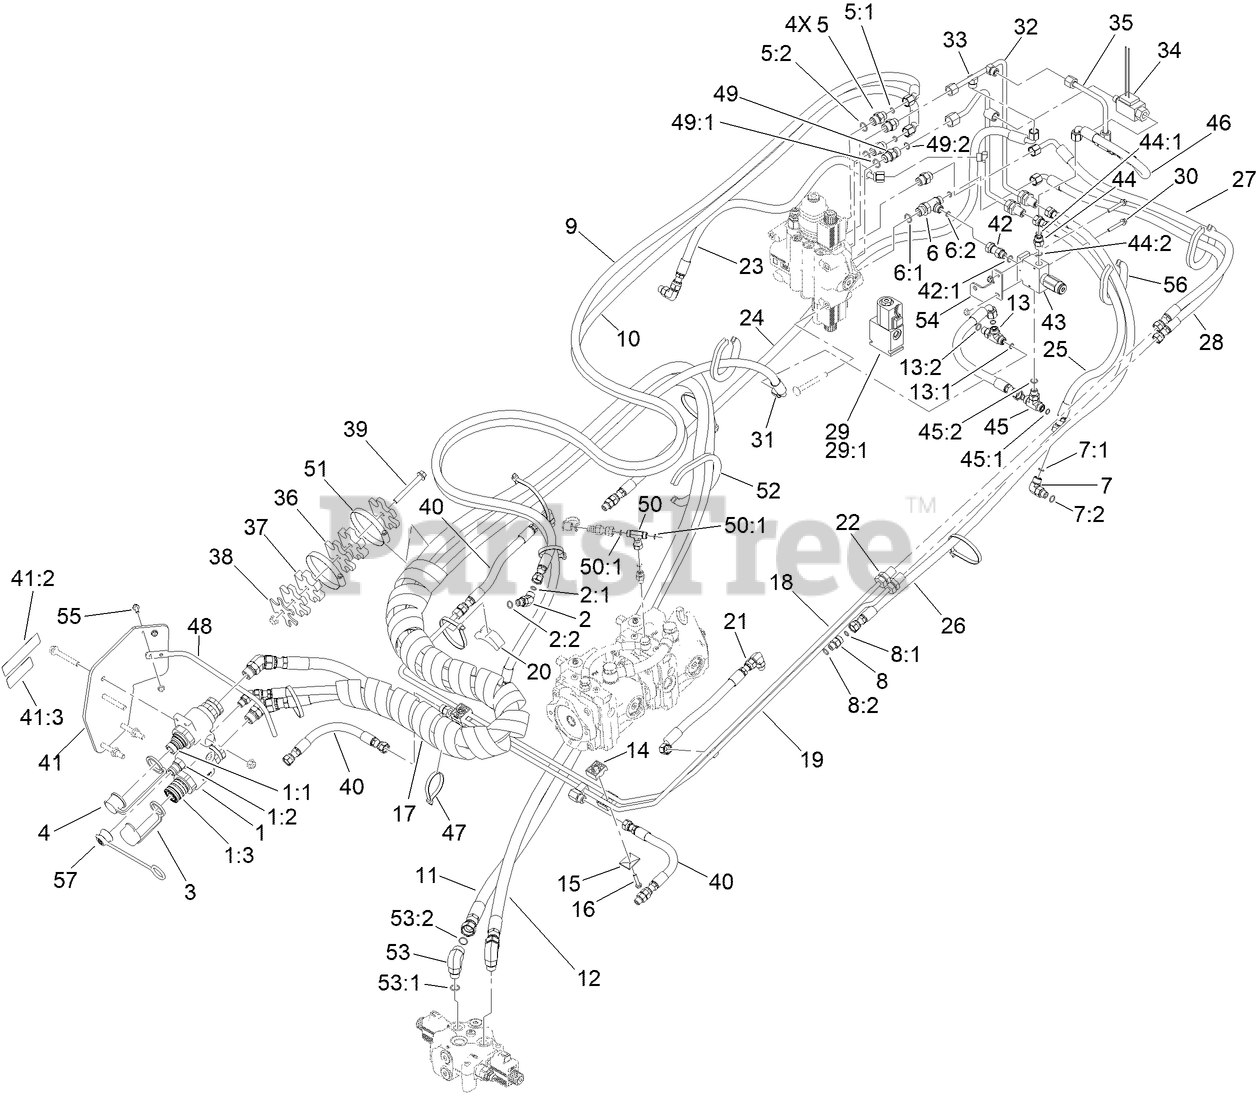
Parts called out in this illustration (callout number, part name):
1	MANIFOLD-QDC
1:1	KIT-MALE COUPLER, 1/2"
1:2	KIT-MALE COUPLER, 3/8"
1:3	KIT-FEMALE COUPLER, 1/2"
2	FITTING-ELBOW, 45 DEG
2:1	O-RING
2:2	O-RING
3	CAP-DUST, COUPLER
4	CAP-DUST, NIPPLE
5	FITTING-STRAIGHT
5:1	O-RING
5:2	O-RING
6	FITTING-HYD, TEE
6:1	O-RING
6:2	O-RING
7	FITTING-ELBOW, 90 DEG
7:1	O-RING
7:2	O-RING
8	FITTING-STRAIGHT
8:1	O-RING
8:2	O-RING
9	HYD HOSE ASM
10	HYD HOSE ASM
11	HYD HOSE ASM
12	HYD HOSE ASM
13	FITTING-TEE
13:1	O-RING
13:2	O-RING
14	CLAMP-HOSE
15	PLATE-CLAMP, RETAINER
16	SCREW-HH
17	WRAP-HOSE
18	HYD TUBE ASM
19	HYD TUBE ASM
20	BLOCK-HARDLINE
21	HYD HOSE ASM
22	NUT-LOCK
23	HYD HOSE ASM
24	HYD HOSE ASM
25	HYD HOSE ASM
26	HYD HOSE ASM
27	HYD HOSE ASM
28	HYD HOSE ASM
29:1	SOLENOID COIL
30	SCREW-HHF
31	HYD HOSE ASM
32	HYD TUBE ASM
33	HYD TUBE ASM
34	SWITCH-PRESSURE,
35	HYD TUBE ASM
36	CLAMP-HOSE
37	CLAMP-HOSE
38	PLATE-BACKER
39	SCREW-HHF
40	HYD HOSE ASM
41	MOUNT-QC
41:2	DECAL-CAUTION
41:3	DECAL-WARNING, HYD PRESSURE
42	CONNECTOR-SWIVEL, STRAIGHT
42:1	O-RING
43	VALVE-SEQUENCE
44	FITTING-STRAIGHT
44:1	O-RING
44:2	O-RING
45	ADAPTER
45:1	O-RING
45:2	O-RING
46	HYD HOSE ASM
47	TIE-CABLE
48	GUIDE-HOSES
49	VALVE-CHECK
49:1	O-RING
49:2	O-RING
50	FITTING-TEE
50:1	O-RING
51	CLAMP-BAND/SCREW
52	TRIM-SEAL
53	FITTING-ELBOW, 90 DEG
53:1	O-RING
53:2	O-RING
54	BRACKET-MOUNT, VALVE
55	SCREW-HHF
56	TRIM-SEAL
57	CAP-DUST, NIPPLE
